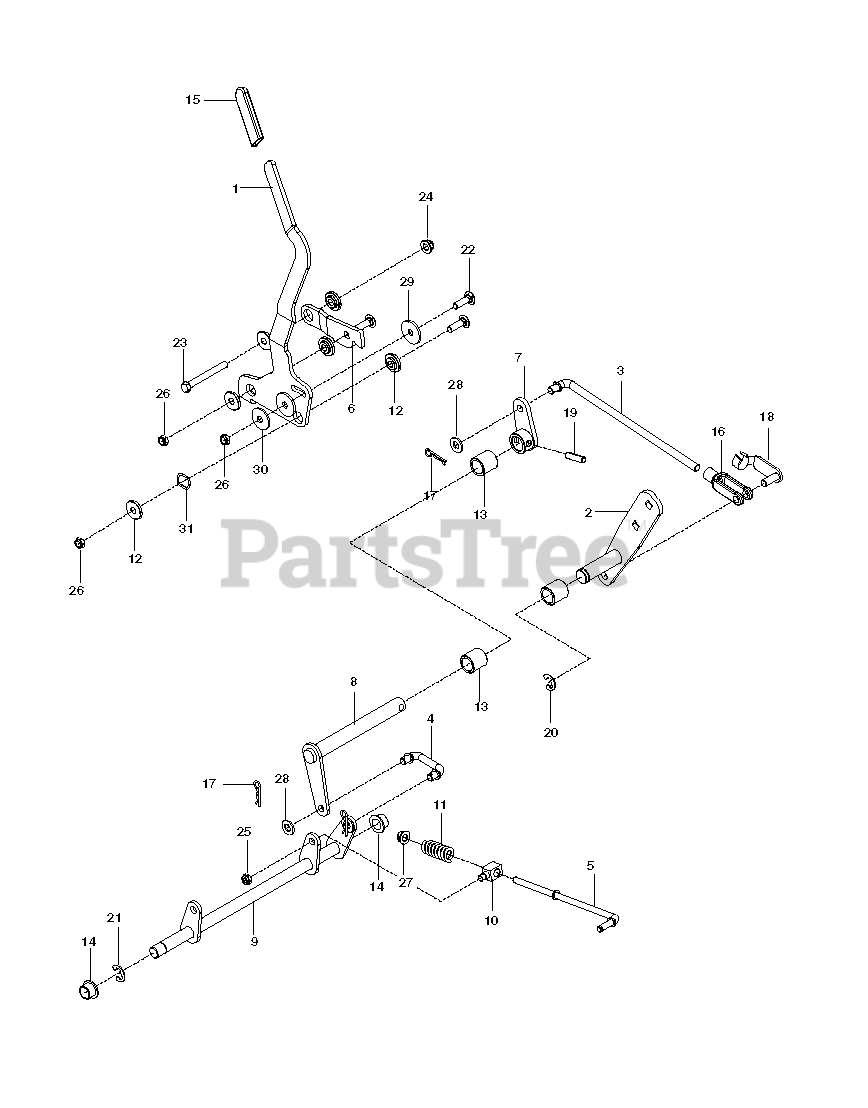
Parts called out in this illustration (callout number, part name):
1	LEVER, BRAKE, BLK
6	LINK, FOLLOWER
7	ARM, RT BRAKE
10	SWIVEL, BRAKE
12	BUSHING, BRAKE
13	BUSHING, SLEEVE 3/4 X 1.0
17	HAIRPIN #2
18	PIN, CLEVIS SPRING, 3/8
19	5/16 DIA ROLL PIN
20	E RING 3/4
21	5/8 E-RING
22	RHSNB 3/8-16 X 1-1/4
23	HCS 3/8-16 X 3-1/4 GR5 ZD
24	NUT 3/8-16 HEX FLG NYLOC ZD
25	5/16-18 THIN PROF NY
26	NUT HEX 3/8-16 NYLON, THIN
27	5/16-18 NYLOC FLANGE NUT
28	WASHER 3/8 SAE FLAT
29	WASHER, FRICTION, 1/8
31	WASHER, .825 X 1.087, WAVE
